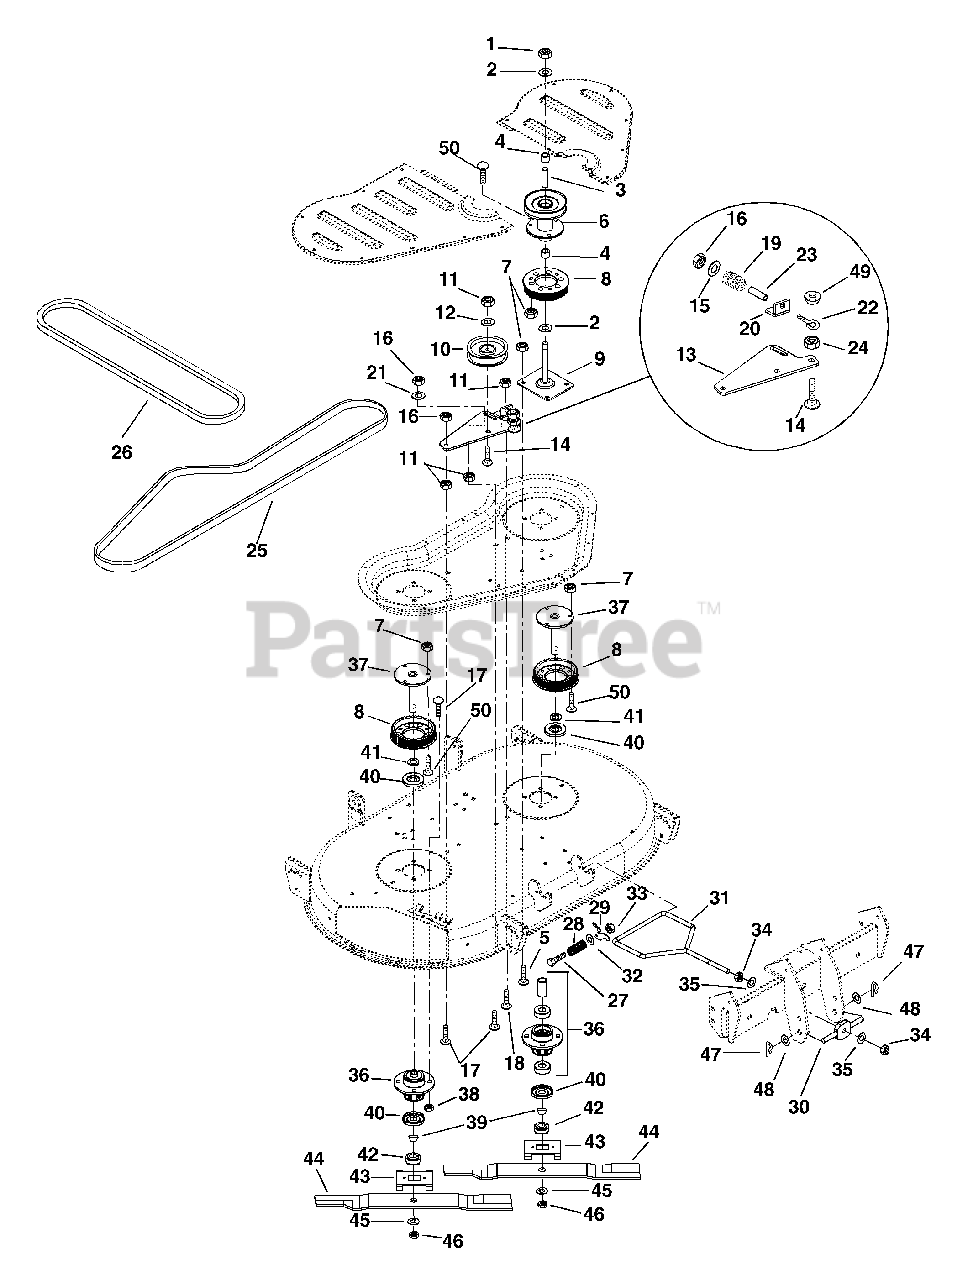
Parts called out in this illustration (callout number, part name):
1	Nut-Locking-Nylon .625-18
2	Washer-Flat-Steel .630 x 1.00 x .062
3	Spacer .64 x .88 x 3.38
4	Bearing .625 x 1.37 x .43
5	Bolt-Round Head Square Neck .31-18 x .75
6	Jackshaft
7	Nut-Locking-Center.31-18
8	Sprocket-Drive
9	Weldment-Plate Mount
10	Assembly-Idler Pulley
11	Nut-Locking-Jam-Center .38-16
12	Washer-Flat-Steel .406 x .812 x .065
13	Arm-Idler
14	Bolt Round Head Square Neck .38-16 x 1.50 Grade 5
15	Washer-Flat-Steel .438 x 1.00 x .083
16	Nut-Locking-Center .38-16
17	Bolt-Round-Head Square Neck .38-16 x 1.25 Grade 5
18	Bolt-Round-Head Square Neck .38-16 x .75 Grade 5
19	Spring-Compression .125 x .78 x 1.25
20	Bracket-Belt Adjustment
21	Washer-Flat-Steel .438 x 1.00 x .083
22	Bolt-Eye .375-16 x 2.50
23	Spacer .39 x .50 x .88
24	Nut-Locking-Nylon .38-16
25	Belt-Cog
26	Belt-V A-RMA
27	Bolt-Hex .25-20 x 1.25 Grade 5
28	Spring-Compression .058 x .68 x .75
29	Retainer-Brace
30	Weldment-Front Mount
31	Rod Link
32	Washer-Flat-Steel .312 x .734 x .065
33	Nut-Locking-Nylon .25-20
34	Nut-Locking-Center ..50-13
35	Washer-Flat-Steel .563 x 1.38 x .109
36	Assembly-Spindle Housing
37	Weldment-Spindle Shaft
38	Nut-Locking-Top-Flange .38-16
39	Key Woodruff .188 x .625 x .31
40	Bearing-Slinger
41	Washer-Flat-Steel .755 x 1.25 x .125
42	Hub-Retainer
43	Tray-Blade
44	Blade-22" (015)
45	Washer-Locking .75 x .188
46	Nut-Jam .75-10
47	Clip-Spring
48	Washer-Flat-Steel .531 x 1.06 x .095
49	Nut-Locking-Flange Grade.A .375-16
50	Bolt-Round-Head Square Neck .31-18 x 1.00 Grade 5
